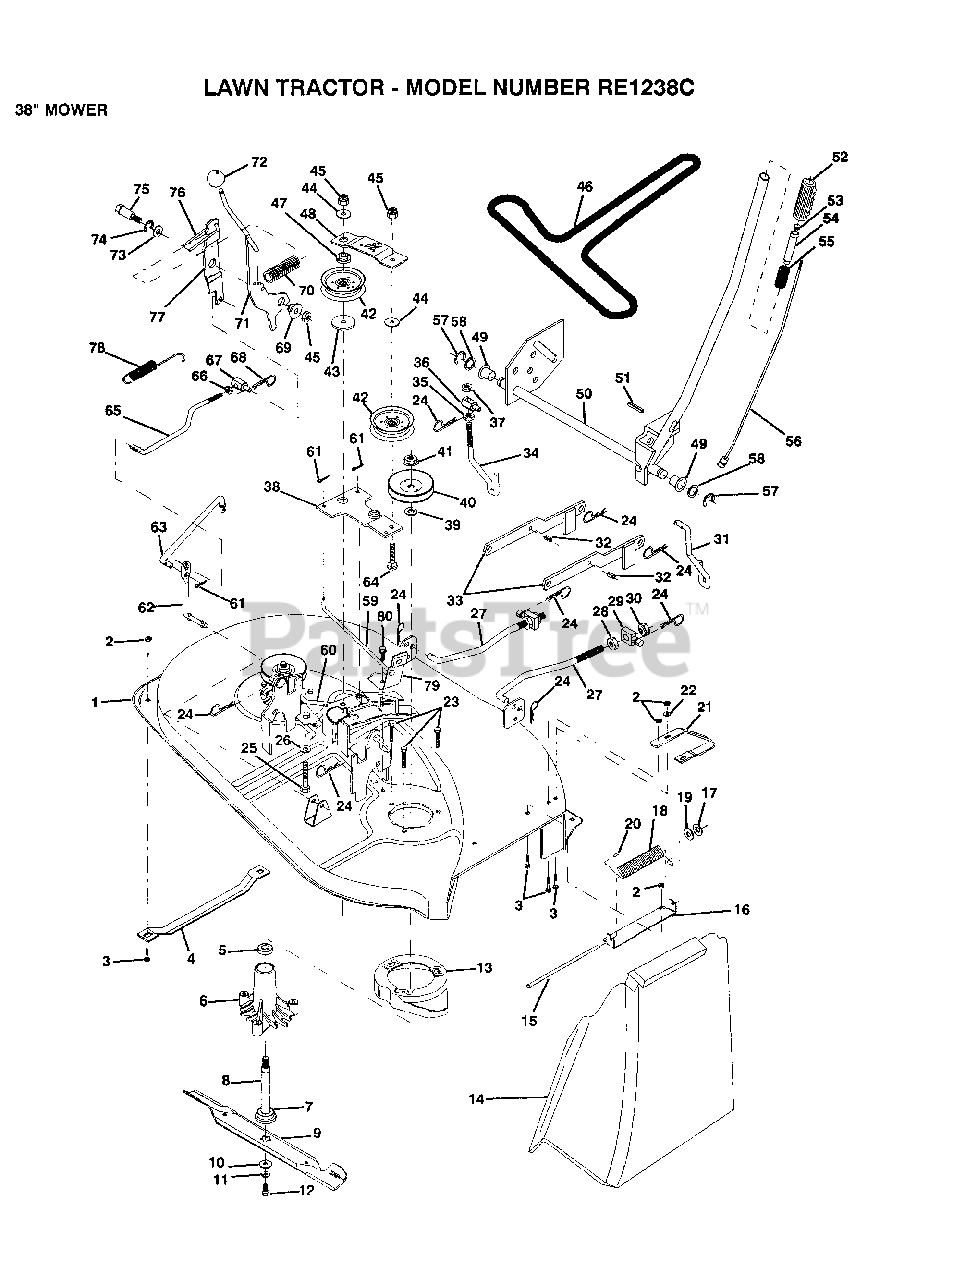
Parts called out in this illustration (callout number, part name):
3	BOLT
4	RUNNER-LH M
5	BEARING
6	HSG ASM MANDREL
7	BEARING.BALL
10	WASHER BLADE
12	BLADE BOLT
14	DEFLECTOR-SHLD T
15	ROD-HINGE T
17	NUT PUSH M
19	WASHER
20	CAP-SLEEVE LT
21	RUNNER RH
22	WASHER M
25	BOLT
26	"WASHER,HARDEN"
27	LINK.FRONT
28	NUT
29	TRUNION
30	NUT LTV
31	LINK LIFT RH
32	SPRING PIN
33	SUSP ARM REAR
34	LIFT LINK LH
35	NUT
39	WASHER
42	FLAT IDLER PULLEY
43	SPACER RETAINER
44	WASHER GT
46	BELT-V.88.12.MW
47	RETAINER SPACER
48	IDLER ARM STIFF
49	NYLON BEARING
51	PIN-GROOVE LT
52	GRIP HANDLE
58	WASHER
59	BRAKE ROD RH
60	BRAKE ROD LH
62	PIVOT ROD
63	CLUTCH ROD SECOND
64	BOLT
66	NUT
67	TRUNION
68	RETAINER M
69	BUSHING
71	CLUTCH ARM PRI AS
72	KNOB T(3/8 HOLE)
73	WASHER
74	RING
75	SHOULDER BOLT
76	SPRING KEEPER
77	CLUTCH ARM SECOND
78	RETURN SPRING
79	BRAKE ASM
80	SCREW
